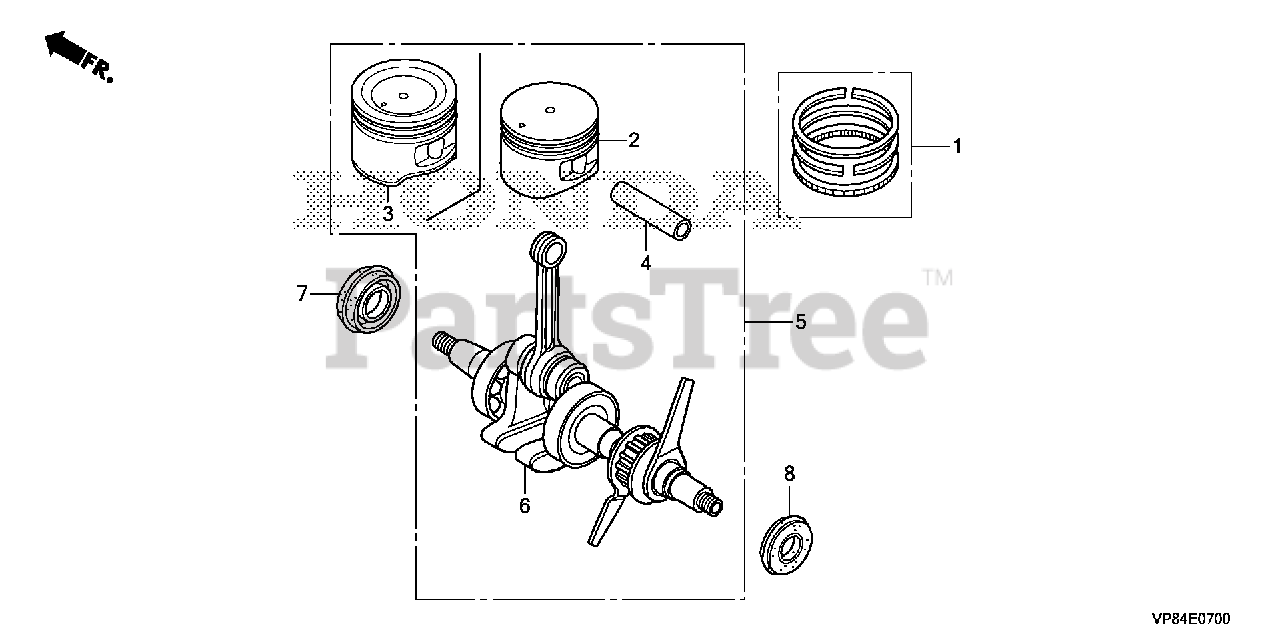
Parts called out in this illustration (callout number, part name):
1	RING SET, PISTON
1	RING SET, PISTON (TPR)
2	PISTON (STD)
4	PIN, PISTON
5	CRANKSHAFT
6	CRANKSHAFT
7	OIL SEAL (12X24X5)
8	OIL SEAL (10X20X5)
